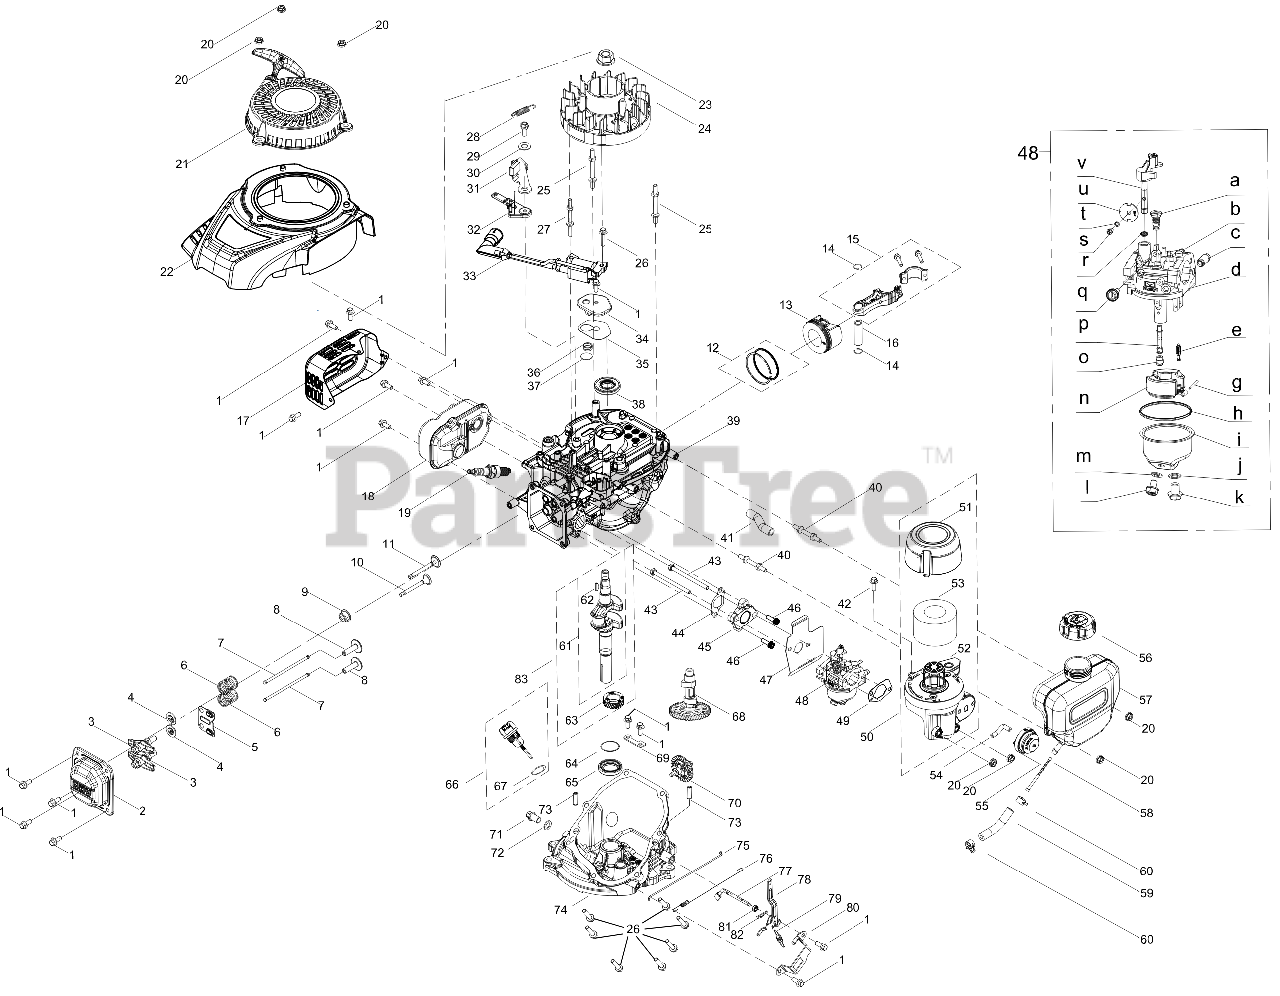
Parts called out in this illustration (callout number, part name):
1	BOLT M6-1 x 14 GR8.8
2	VALVE COVER
3	ROCKER ARM ASSEMBLY
4	VALVE SPRING RETAINER
5	PUSH ROD GUIDE
6	VALVE SPRING
7	PUSH ROD
8	TAPPET (LIFTER)
9	INTAKE VALVE SEAL
10	EXHAUST VALVE
11	INTAKE VALVE
13	PISTON RING SET
14	SNAP RING-PISTON PIN
15	CONNECTING ROD
16	PISTON PIN
17	MUFFLER GUARD
19	SPARK PLUG
21	STARTER RECOIL ASSEMBLY
22	ENGINE SHROUD
23	FLYWHEEL NUT
24	FLYWHEEL
25	STUD M6 x 75
26	BOLT M6-1 x 25 GR8.8
27	STUD M6 x 73
28	ENGINE BRAKE SPRING
29	ENGINE BRAKE PIN M6-1.0 MM
30	FLAT WASHER 10x20x1.0 MM
31	ENGINE BRAKE ARM
32	ENGINE BRAKE LOWER BRACKET
33	IGNITION COIL
34	BREATHER COVER PLATE
35	BREATHER GASKET
36	BREATHER VALVE SPRING
37	BREATHER VALVE
38	UPPER CRANKSHAFT SEAL
39	CRANKCASE
40	FUEL TANK MOUNTING STUD M6X59.5
41	BREATHER HOSE
42	BOLT M6 x 16
43	BOLT M6X80
44	CARBURETOR INSULATION GASKET
45	CARBURETOR INSULATOR
46	BOLT M6X20
47	CARBURETOR GASKET
48	CARBURETOR
49	AIR FILTER BASE GASKET
50	AIR FILTER ASSEMBLY
51	AIR FILTER COVER
52	AIR FILTER BASE
53	AIR FILTER - FOAM
54	PRIMER HOSE
55	VENTED PRIMER ASSEMBLY
56	FUEL CAP ASSEMBLY
57	FUEL TANK
58	FUEL FILTER
59	FUEL HOSE
60	HOSE CLAMP
61	CRANKSHAFT
62	FLYWHEEL KEY
63	CRANKSHAFT TIMING GEAR
64	THRUST WASHER
65	LOWER CRANKSHAFT SEAL
66	DIPSTICK ASSEMBLY
67	DIPSTICK SEAL
68	CAMSHAFT
69	GOVERNOR GEAR MOUNTING PLATE
70	GOVERNOR GEAR/SHAFT ASSEMBLY
71	OIL DRAIN PLUG
72	WASHER
73	DOWEL PIN 7X20
74	CRANKCASE COVER
75	THROTTLE LINKAGE
76	THROTTLE LINKAGE SPRING
77	GOVERNOR ARM SHAFT
78	GOVERNOR ARM ASSEMBLY
79	GOVERNOR SPRING
80	COMPONENT BRACKET
81	GOVERNOR SEAL
82	COTTER PIN
83	CRANKSHAFT ASSEMBLY
